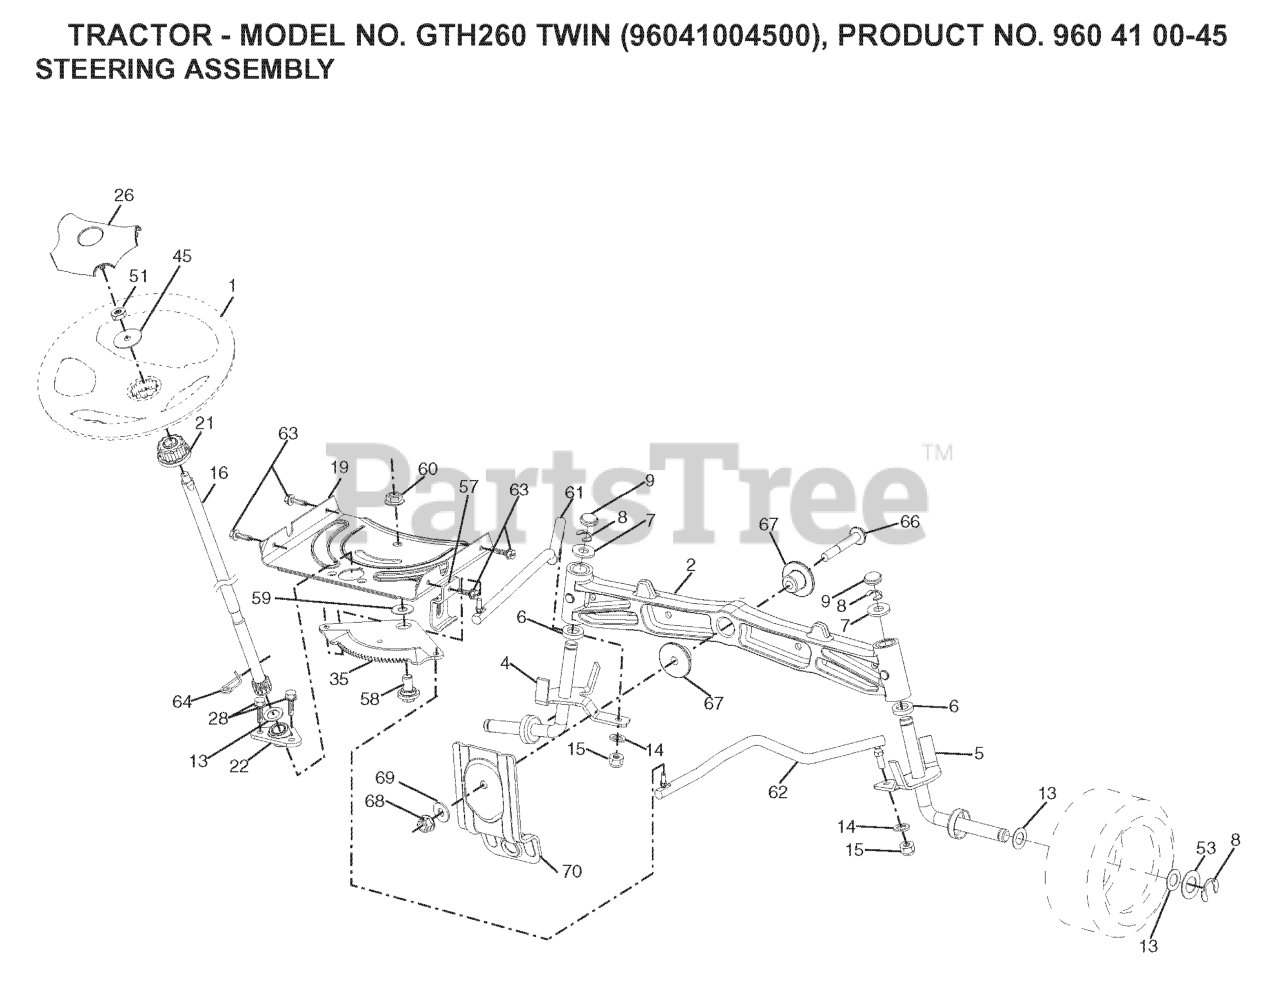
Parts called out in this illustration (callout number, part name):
1	STEERING WHEEL
2	AXLE.CAST.IRON
4	SPINDLE.WELDED.LH.16"TEX
5	SPINDLE.WELDED.RH.16"TEX
6	THRUST WASHER
9	CAP.SPINDLE.BLACK
14	WASHER, LOCK 3/8
15	NUT CROWNLOCK 3/8-24
16	SHAFT.STEER.STEALTH.DD
19	PLATE.STEER.DDL.NLT/NG
21	ADAPTER, WHEEL STNG..
22	BUSHING.ASM.STEERING.A
26	INSERT.CAP.STRG.WH.GRAY
28	SCREW, 3/8-16X3/4
35	GEAR.SECTOR.PLATE.DDL.
45	WASHER 9/16"ID, 2 3/8"OD
51	NUT.HEX.1/2-20
53	WASHER.HARDENED
57	BRKT.UPSTOP.GT/LT.TEX
58	BOLT.SHOULDER.SECTOR.P
59	WASHER.THURST.SECTOR.S
60	NUT FLANGE LOCK 5/8-11
61	DRAGLINK.LH.BALLSTUD.D
62	DRAGLINK.RH.BALLSTUD.D
63	SCREW
64	RETAINER.CLIP.SPRING.S
66	BOLT HEX FGHD 7/16-14 X 3 SERR
67	BUSHING.PM.FRONT AXLE
68	NUT.LOCK.FLANGE.7/16
69	WASHER.1.5X.505X.118
70	BRKT.DECK.SUSPENSION.F
